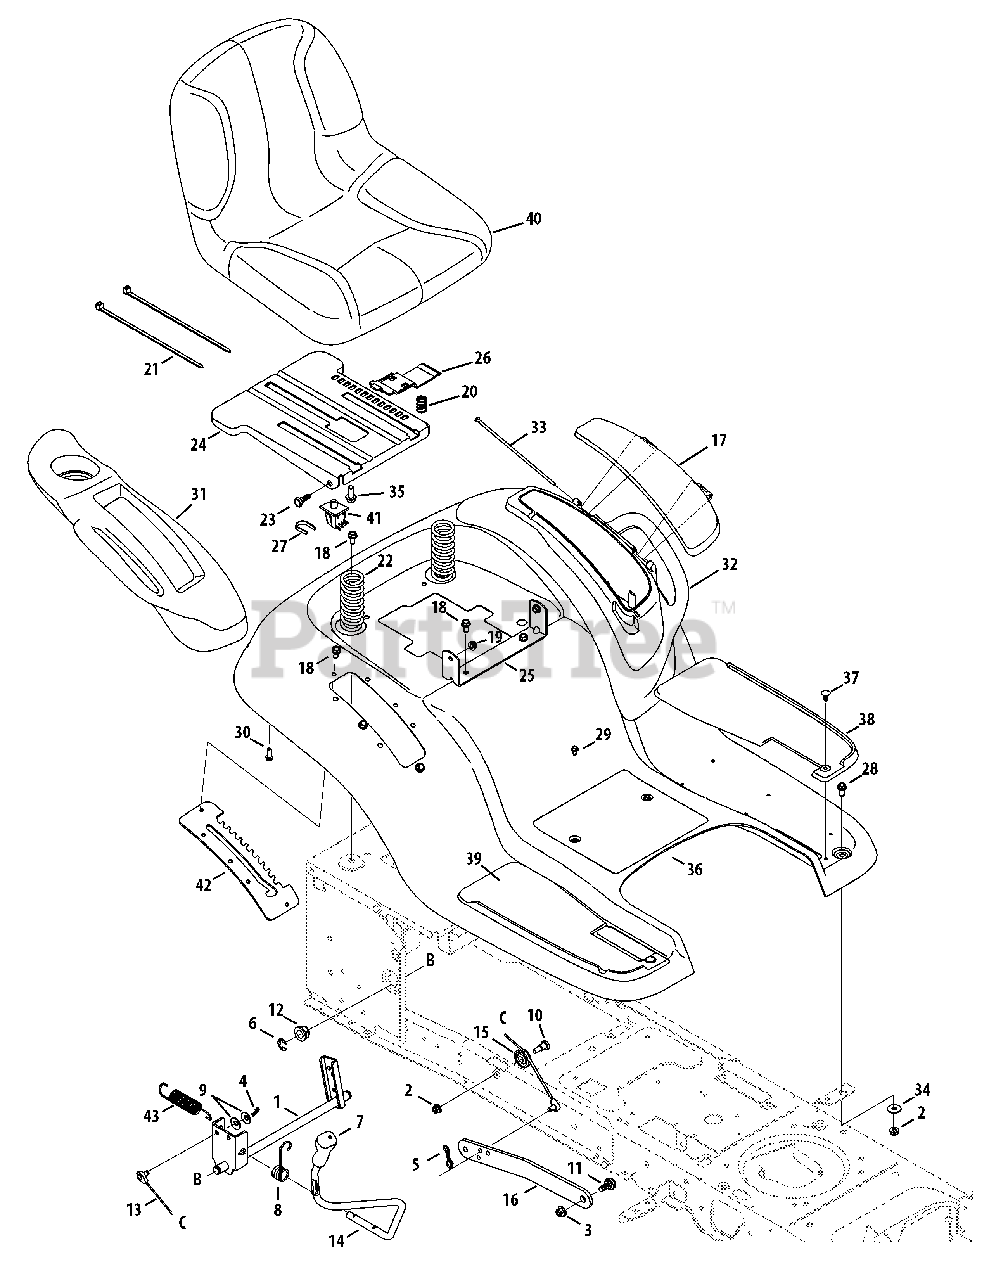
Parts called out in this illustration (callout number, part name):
1	Shaft Ass’y, Lift
2	Nut, Flange Lock, 5/16-18, Grf
3	Nut, Flange Lock, 3/8-16, Grf
4	Pin, Cotter, .072 Dia. x 1.13
5	Pin, Cotter, Bow-Tie 72
6	Ring, E Type, .625 Dia. Shaft
7	Grip, Handle, Cub, .50 ID
8	Spring, Torsion
9	Washer, Spring, .401 x .870 x .063
10	Screw, Shoulder, .437 x .470, 5/16-18
11	Bolt, Shoulder, .50, 3/8-16
12	Bearing, Hex Flange
13	Cable, Lift, 16.16
14	Handle, Lift,
15	Pulley, Roller, Cable
17	Door, Cover, Fender
18	Screw, Self-tapping, 5/16-18, .750,
19	Nut, Flange Lock, 5/16-18, Gr5, Sd Lk
20	Spring, Compr’, .68 x 1.065 x .055
21	Cable, Tie, 3/16 x .05 x 7.4
22	Spring, Comprs, 1.50 x 3.90 x .200
23	Screw, Shoulder, .437 x .268, 5/16-18
24	Bracket, Mounting, Seat
25	Bracket, Pivot, Seat
26	Lever, Seat Adjustment
27	Clip, Retaining, Switch
28	Hex Screw, 5/16-18, .75, Gr5, Std
29	Screw, Self-tapping, 1/4-20, 0.500,
30	Screw, HL, 1/4-15, 0.750,
31	Cover, Fender, RH
32	Cover, Fender, LH
34	Washer, Flat .344 x 1.00 x .063
35	Hex Flange Screw, 3/8/16, .875, Gr5
36	Fender, Cub Hydro
37	Clip, Ratchet, .250 Dia
38	Pad, Foot, LH
39	Pad, Foot, RH
40	Seat, High Back Cloth, Cub
41	Switch, Seat
42	Bracket, Lift
43	Spring, Extension, 1.15 OD x 5.99
